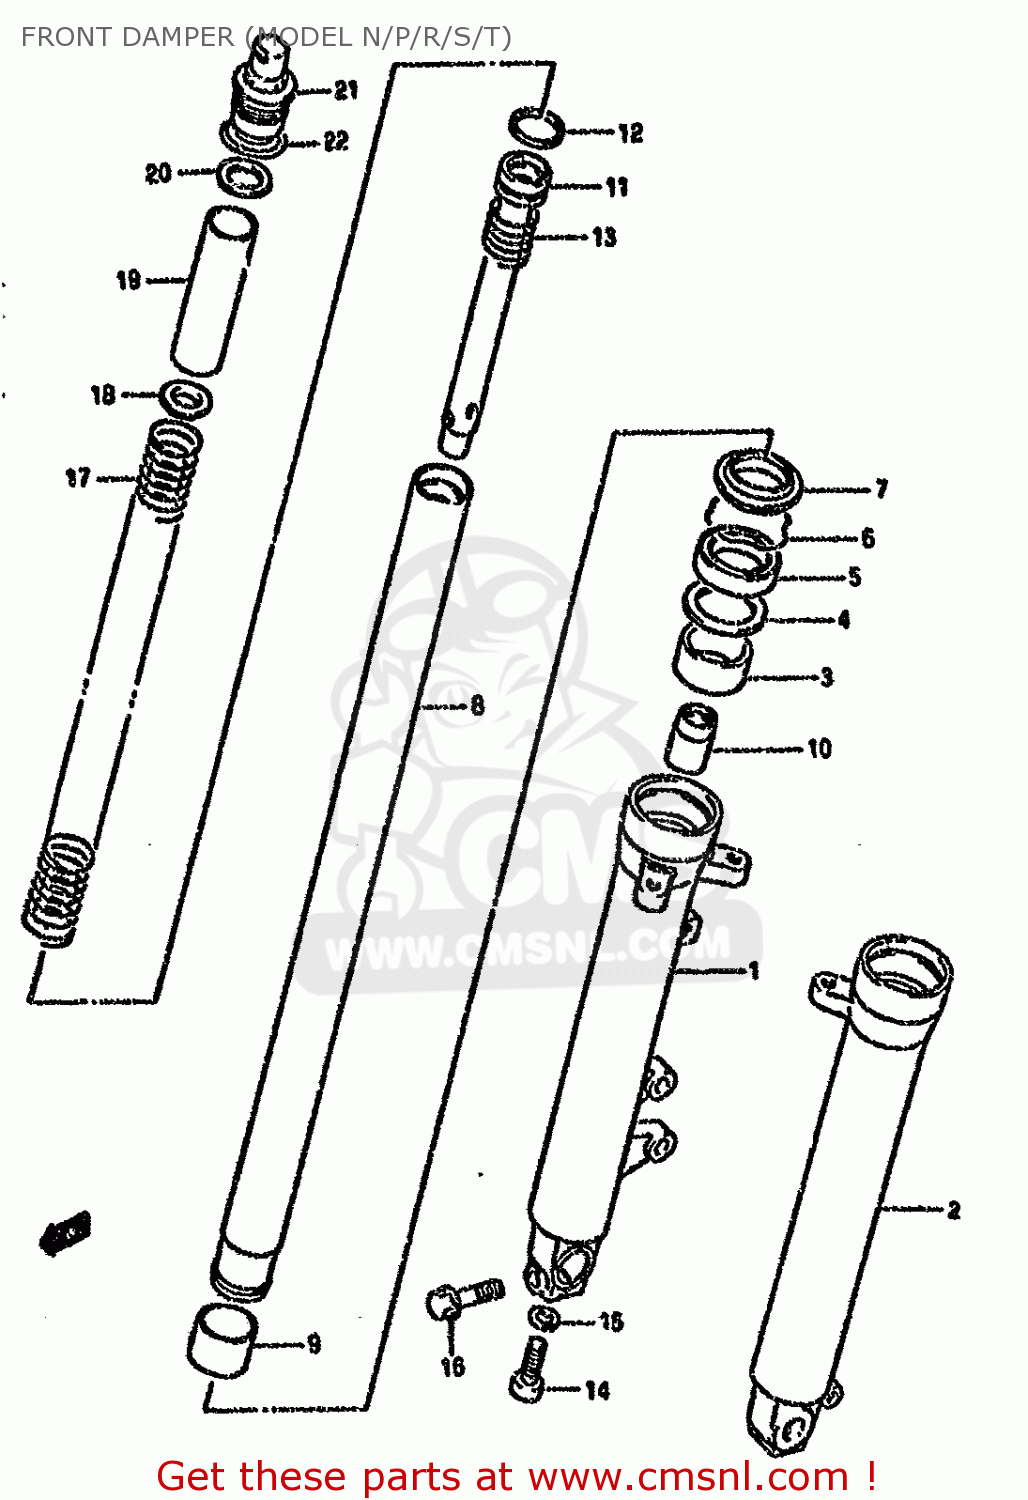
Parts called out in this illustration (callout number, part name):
1	TUBE,OUTER,RIGHT
2	TUBE,OUTER,LEFT
3	METAL,SLIDE
4	WASHER
5	OIL SEAL,FRONT FORK
6	RING,STOPPER
7	DUST SEAL,FRONT FORK
8	TUBE,INNER
9	PISTON
10	PIECE,OIL LOCK
11	CYLINDER
12	RING,PISTON
13	SPRING,REBOUND
14	BOLT,FORK CYLINDER(10X25)
15	GASKET (NAS)
16	BOLT
17	SPRING,MAIN
18	GUIDE
19	SPACER,FR FORK SPRING
20	BOLT,FORK
21	O RING
22	O RING
